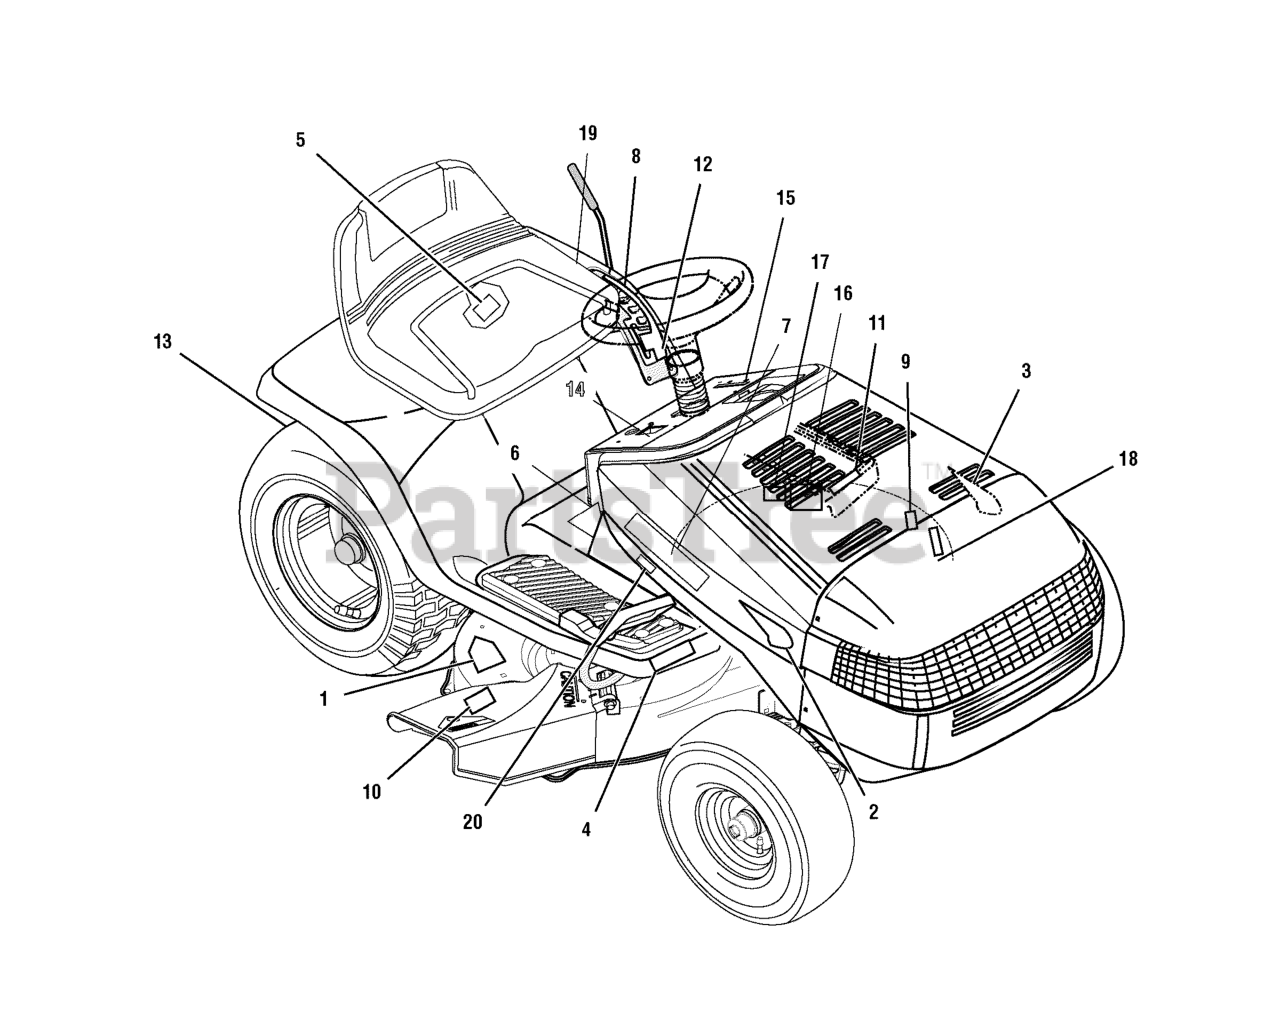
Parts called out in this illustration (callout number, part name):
1	DECAL ENGLISH CUT FINGER
2	DECAL, MASPORT 17.5/42 RH
3	DECAL, MASPORT 17.5/42 LH
4	DECAL, V3-DC-5X2 HYDRO DRIVE
5	DECAL, HYDRO RELEASE DOM
6	DECAL, WARNING
7	DECAL, MASPORT LOGO
8	DECAL, 1/6 HGT ADJUST LIFT LGSD
9	DECAL, NO STEP, LH HSNG
10	DECAL, NO STEP, CHUTE
11	DECAL, BRAKE/PARK BRAKE
12	DECAL, DECK LEVEL POS/ONLY
13	DECAL, WARNING LOAD LMT
14	DECAL, IGNITION ENGAGE PRK BRK (NMR)
15	DECAL, THROTTLE SNGLE W/CHOKE
16	DECAL, GAGE WHEEL INST
17	DECAL, GAGE WHEEL LEVELING
18	DECAL, 3 WAY
19	DECAL, ENGAGE PTO
20	DECAL, V2-SS-1X3 CUTTING HEIGHT
